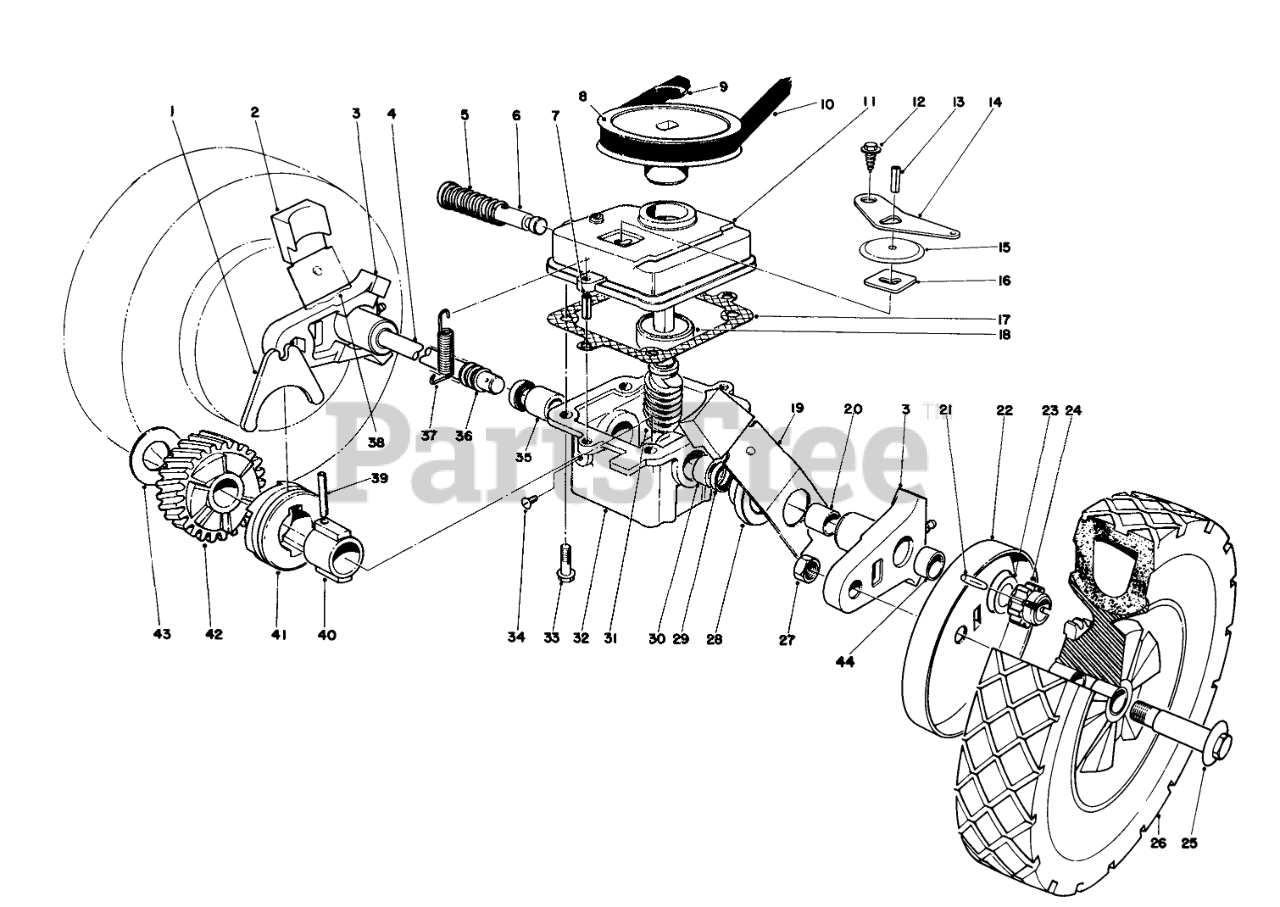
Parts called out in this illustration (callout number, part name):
1	SHIFTER FORK
2	KNOB-ARM
3	Pivot Arm (Incl. Ref. #20 & 44)
4	DRIVE SHAFT (SERVCE)
5	SPRING
6	Shift Rod
7	3/16 X 1/2 ROLL PIN
8	PULLEY
9	PUSH-ON 93-3236
10	V BELT
11	Cover Gear Case
12	Screw
13	PIN-ROLL
14	SHIFTER ARM
15	TRANS DUST COVER
16	LATCH PLATE
17	GASKET
18	Bearing
19	SPRING ARM ASM SP LH
20	BUSHING
21	Pin
22	WHEEL COVER
23	WASHER-THRUST
24	Pinion
25	BOLT-WHEEL
26	Wheel & Tire Assembly
27	Nut
28	End Cap
29	Seal
30	Bushing
31	Worm Shaft & Gear (Incl. Ref. #42)
32	Gear Case (Incl. Ref. #29-30 & 35)
33	Screw
34	NYLON SCREW
35	Bushing
36	COVER-SHAFT, DRIVE
37	TENSION SPRING
38	SPRING ARM ASM SP RH
39	COIL PIN
40	SLEEVE
41	CLUTCH JAW
42	Helical Gear
43	THRUST WASHER
44	BUSHING
